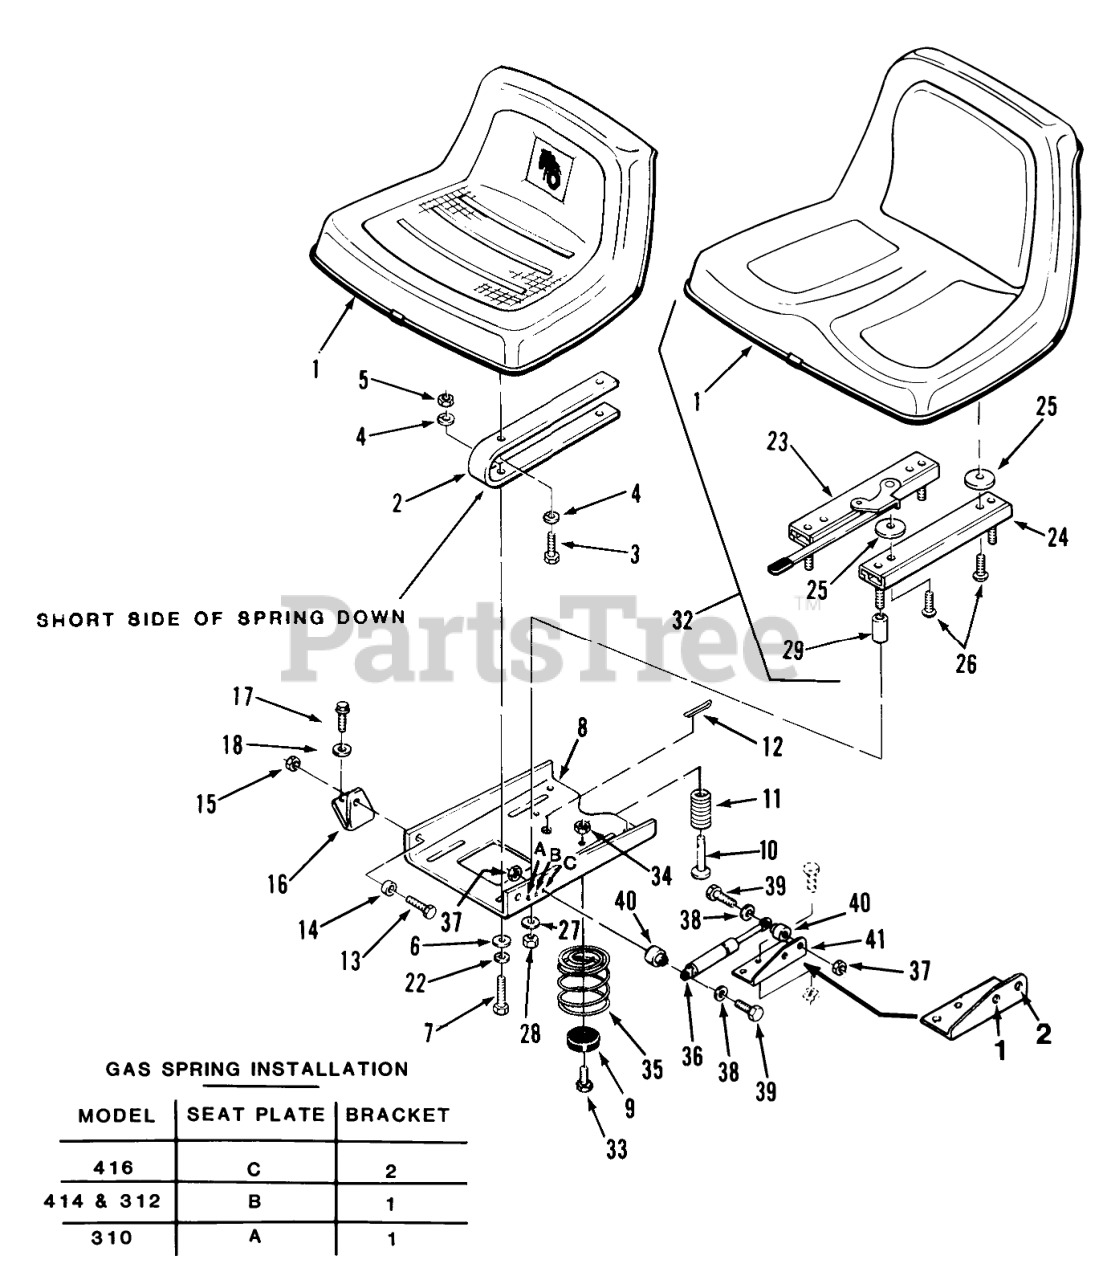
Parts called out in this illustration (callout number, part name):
1	Seat
2	Seat Spring
3	Bolt
4	Lockwasher
5	Nut
6	WASHER 5/16 SAE
7	HHCS
8	PLATE-SEAT PIVOT B
9	BUMPER
11	SPRING-SEAT SWITCH
12	Cotter Pin
13	HHCS
14	BUSHING
15	Nut
16	Bracket-Pivot RH
16	BRACKET-PIVOT L.H B
17	Bolt
18	WASHER 5/16 SAE
22	Lockwasher
23	Adjuster-Seat
24	ADJUSTER-R.H. SEAT
25	SPACER-NYLON
26	Screw
27	Collar
28	Nut
29	SPACER
32	Deluxe Seat Assy (Includes Items 1, 23, 24, 25, 26 & 29)
33	Bolt
34	Nut
35	SPRING-SEAT NYLON
35	SPRING
35	Seat Spring
36	GAS SPRING
37	Nut
39	Bolt
40	SPACER
41	BRACKET-CYLINDER R
